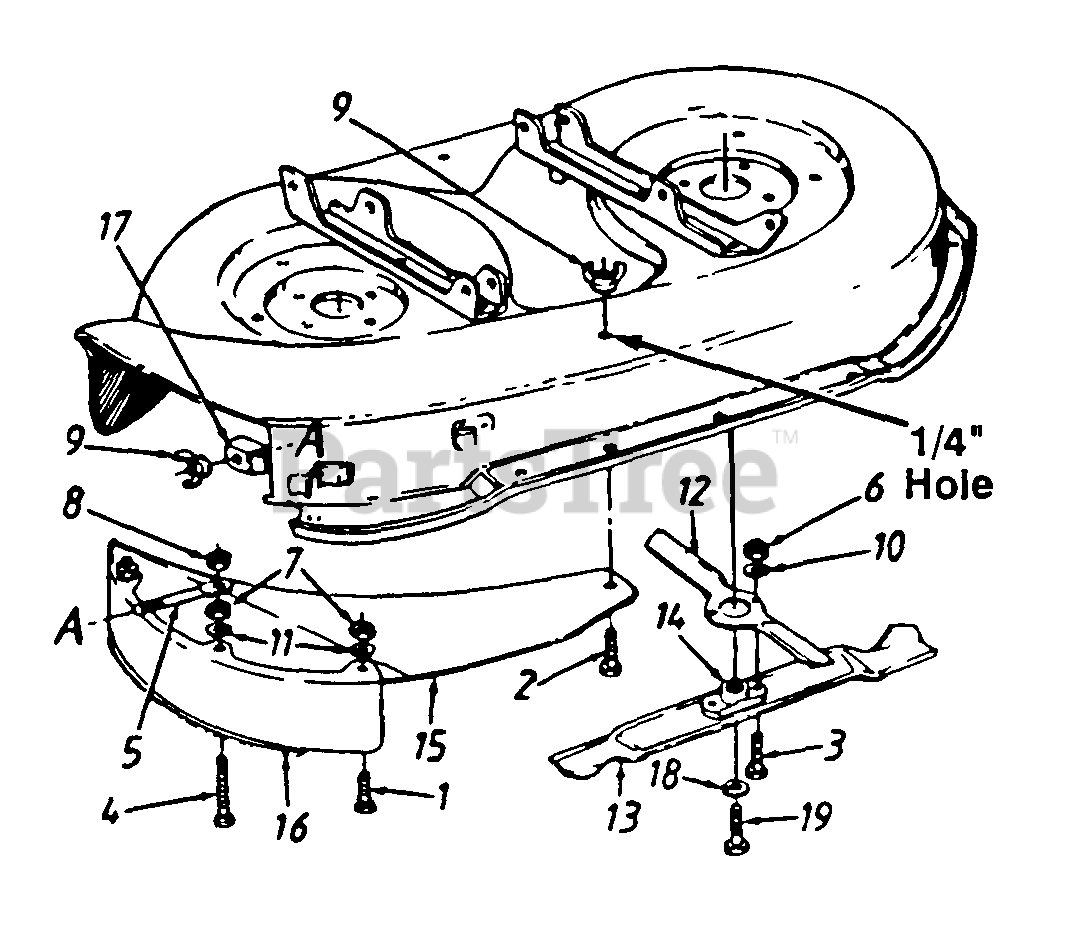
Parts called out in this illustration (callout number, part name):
1	Carriage Bolt 1/4-20 x .62" Lg.
2	Hex Bolt 1/4-20
3	Hex Bolt 7/16-20 x 1.25" Lg. (Gr. 5)
4	Carriage Bolt 1/4-20 x 1" Lg.
5	Retaining Bolt
6	Hex Nut 7/16-20 Thd.
7	Hex Nut 1/4-20 Thd.
8	Hex L-Nut 1/4-20 Thd.
9	Wing Nut
10	L-Wash. 7/16" I.D.
11	L-Wash. 1/4" I.D.
12	Mulching Blade 12.5"
13	Mulching Blade 19.38"
14	Blade Adapter
18	L-Wash. 3/8" I.D.
19	Hex Bolt 3/8-24 x 1" Lg. (Gr. 8)
